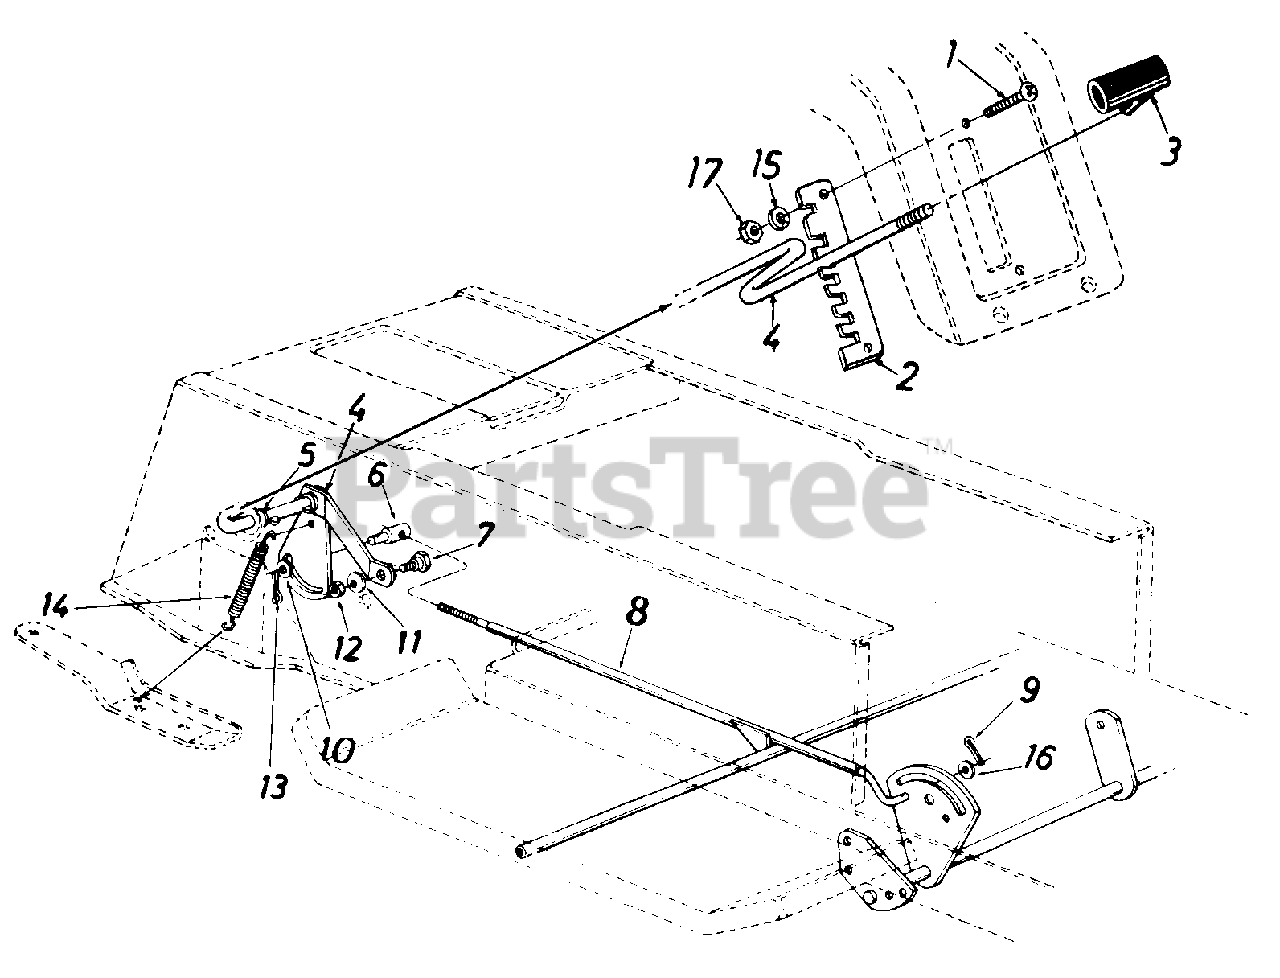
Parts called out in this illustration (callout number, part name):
1	Truss Mach. Scr. 1/4-20 x .62" Lg.
2	Speed Selector Plate
3	Gear Shift Knob
4	Speed Selector Cam Ass'y.
5	Flat Washer .53" I.D. x .93" O.D.
6	Ferrule 3/8-24 x .37" Dia.
7	Shoulder Bolt .435" Dia. x .160
8	Speed Control Rod Ass'y.
9	Cotter Pin 3/32" Dia. x .75" Lg.
10	Fl-Wash. .385" I.D. x .62" O.D.
11	L-Wash. 5/16" I.D.
12	Hex Nut 5/16-18 Thd.
13	Cotter Pin 3/32" Dia. x .75" Lg.
14	Spring .38" O.D. x 3.18" Lg.
15	L-Wash. 1/4" I.D.
16	Fl-Wash. .469" I.D. x .88" O.D.
17	Hex Nut 1/4-20 Thd.
